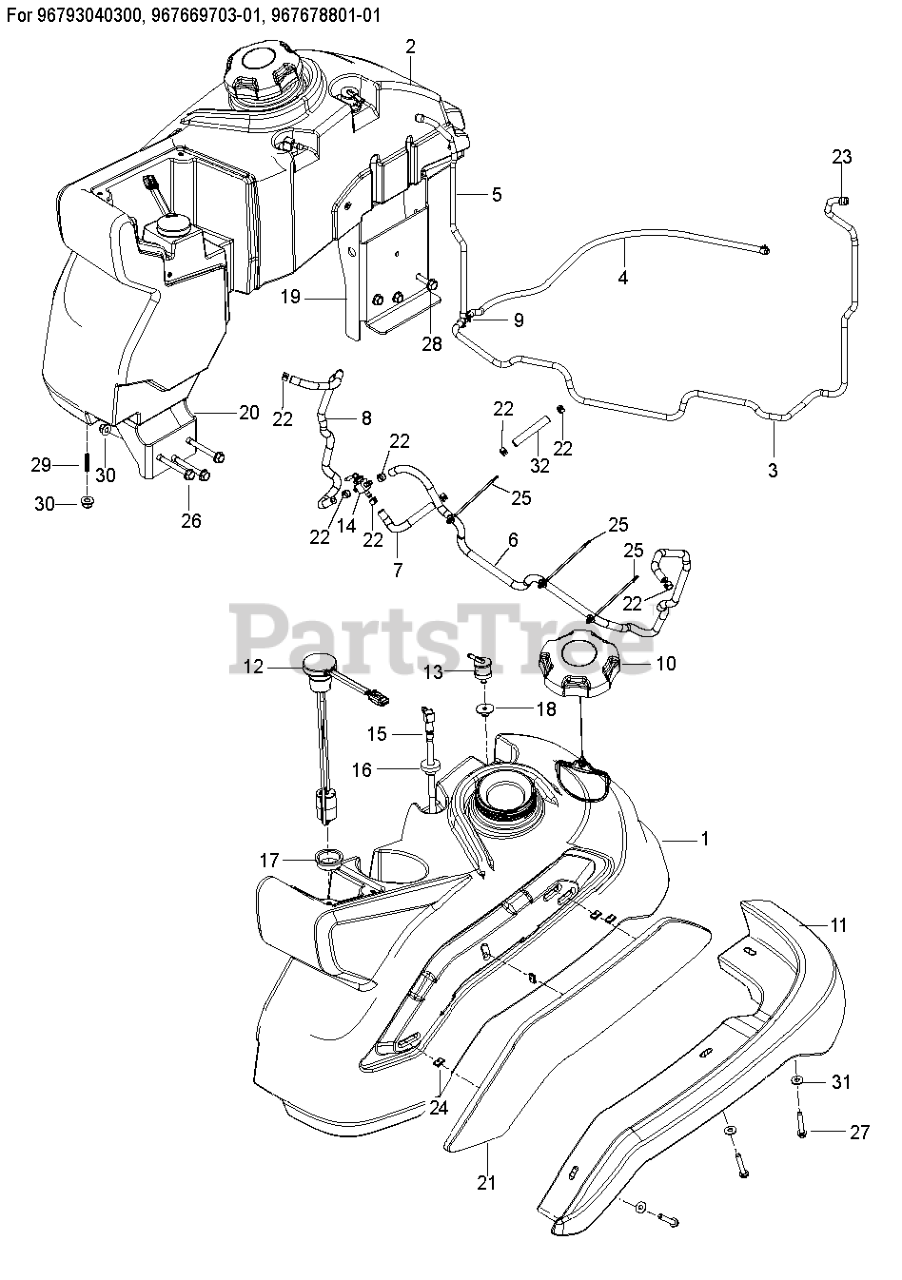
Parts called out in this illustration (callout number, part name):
1	FUEL.TANK.ASM.LH.PZ.REFRESH.18
1	TANK UNIT ASSY LH 2018 PROD. Y
2	TANK UNIT ASSY RH 2018 PROD. Y
2	FUEL.TANK.ASM.RH.PZ.REFRESH.18
3	HOSE 3/16" VAPOR LINE 41" LENG
4	HOSE 3/16" VAPOR LINE 7" LENGT
5	HOSE.3/16".VAPOR.LINE.17"LGTH
6	HOSE 1/4" LOW PERMEATION FUEL
7	HOSE.1/4".LOW.PERM.FUEL.LN.8"
7	HOSE.1/4".LOW.PERM.FUEL.LN.37"
8	HOSE.1/4".LOW.PERM.FUEL.LN.24"
9	TEE, FUEL LINE 3/16"
10	CAP, FUEL
11	GUARD.MUD.LH
12	SENSOR.FUEL.LVL.FLOAT.V500
13	VALVE.FUEL.CHECK
14	FUEL VALVE
15	TUBE.ASM.FUEL.TANK.PICK-UP.LH
16	BUSHING OUTLET T
17	GROMMET, FUEL SENSOR
18	GROMMET.CHECK.FUEL
19	BRACKET.FUEL.TANK.REAR.SUP.431
20	BRACKET.FUEL.TANK.REAR.SUP.431
21	COVER.LH.FUEL.TANK/CONSOLE APP
22	HOSE CLAMP
23	CLAMP, HOSE
24	CLIP.U-TYPE
25	TIE WRAP, 8-3/8", W/CLIP
25	CABLE.TIE.6".FIRTREE.PZ.REFRES
26	BOLT HEX FLGHD 5/16-18X3 GR. 5
27	SCREW.1/4-20X1.5IN.HEX.MACH
28	SCREW
29	SCREW.5/16-18X1.25"THREADED
30	5/16-18 NYLOC FLANGE NUT
31	WASHER
32	HOSE.1/4".LOW.PERM.FUEL.LN.3"
